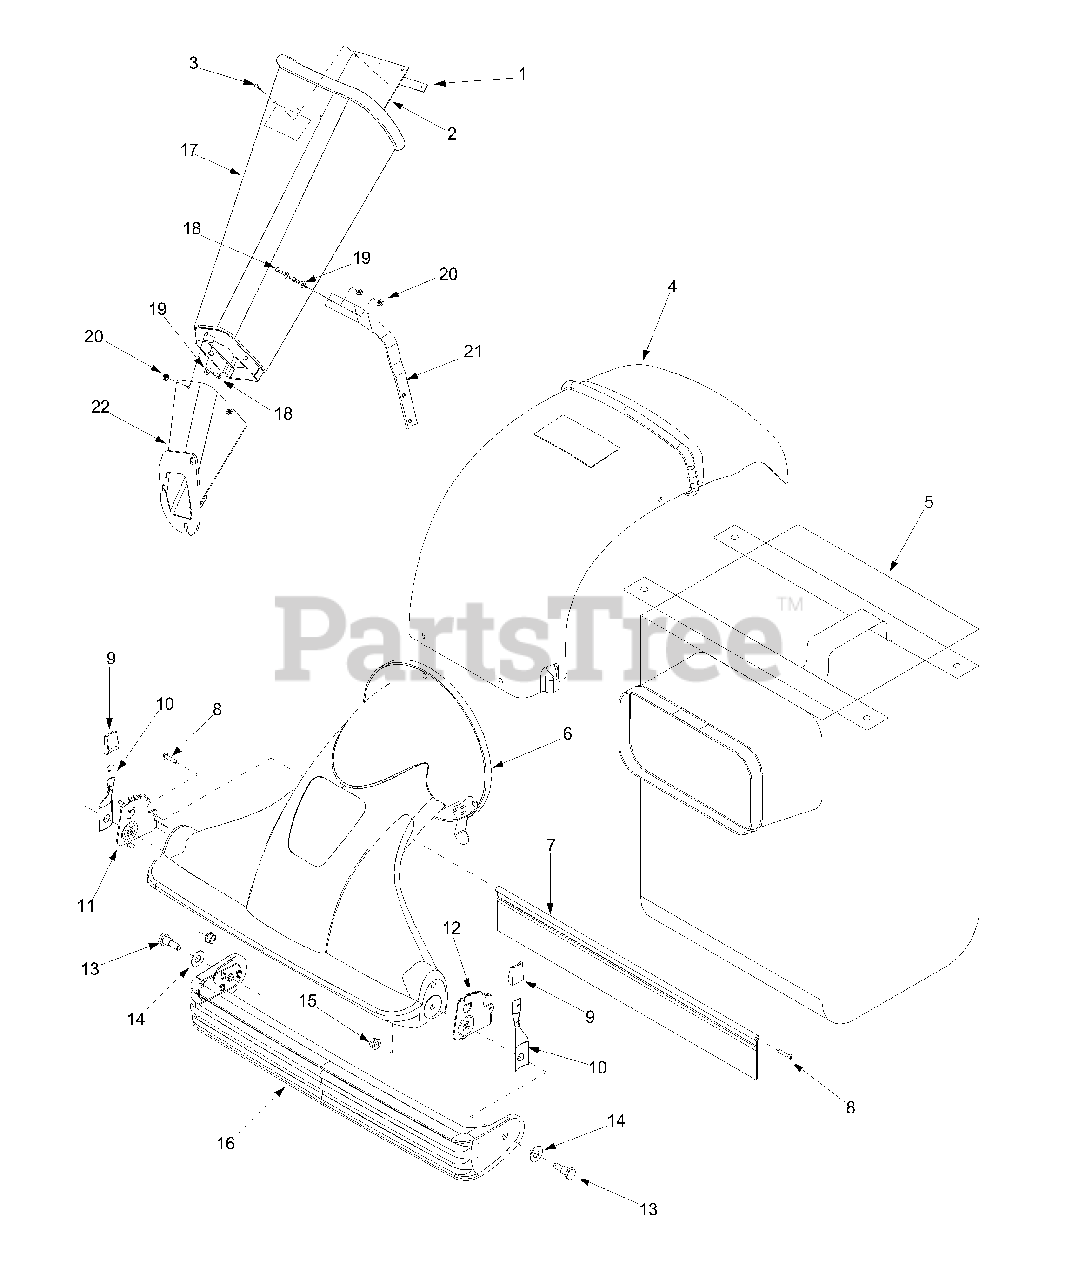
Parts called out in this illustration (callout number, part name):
1	Chute Flap Strip
2	Chute Flap
3	Pop Rivet
4	Discharge Chute
5	Bag
6	Nozzle Assembly
7	Nozzle Flap
9	Height Adjustment Knob
10	Spring Lever
13	Shoulder Screw
14	Flat Washer .510 x 1.12 x .060
15	Hex Flange Lock Nut 3/8-16
16	Door Assembly
17	Chipper Chute
18	Hex Cap Screw 1/4-20 x .620
19	Flat Washer .28 ID x .74 OD
20	Hex Lock Nut 1/4-20
